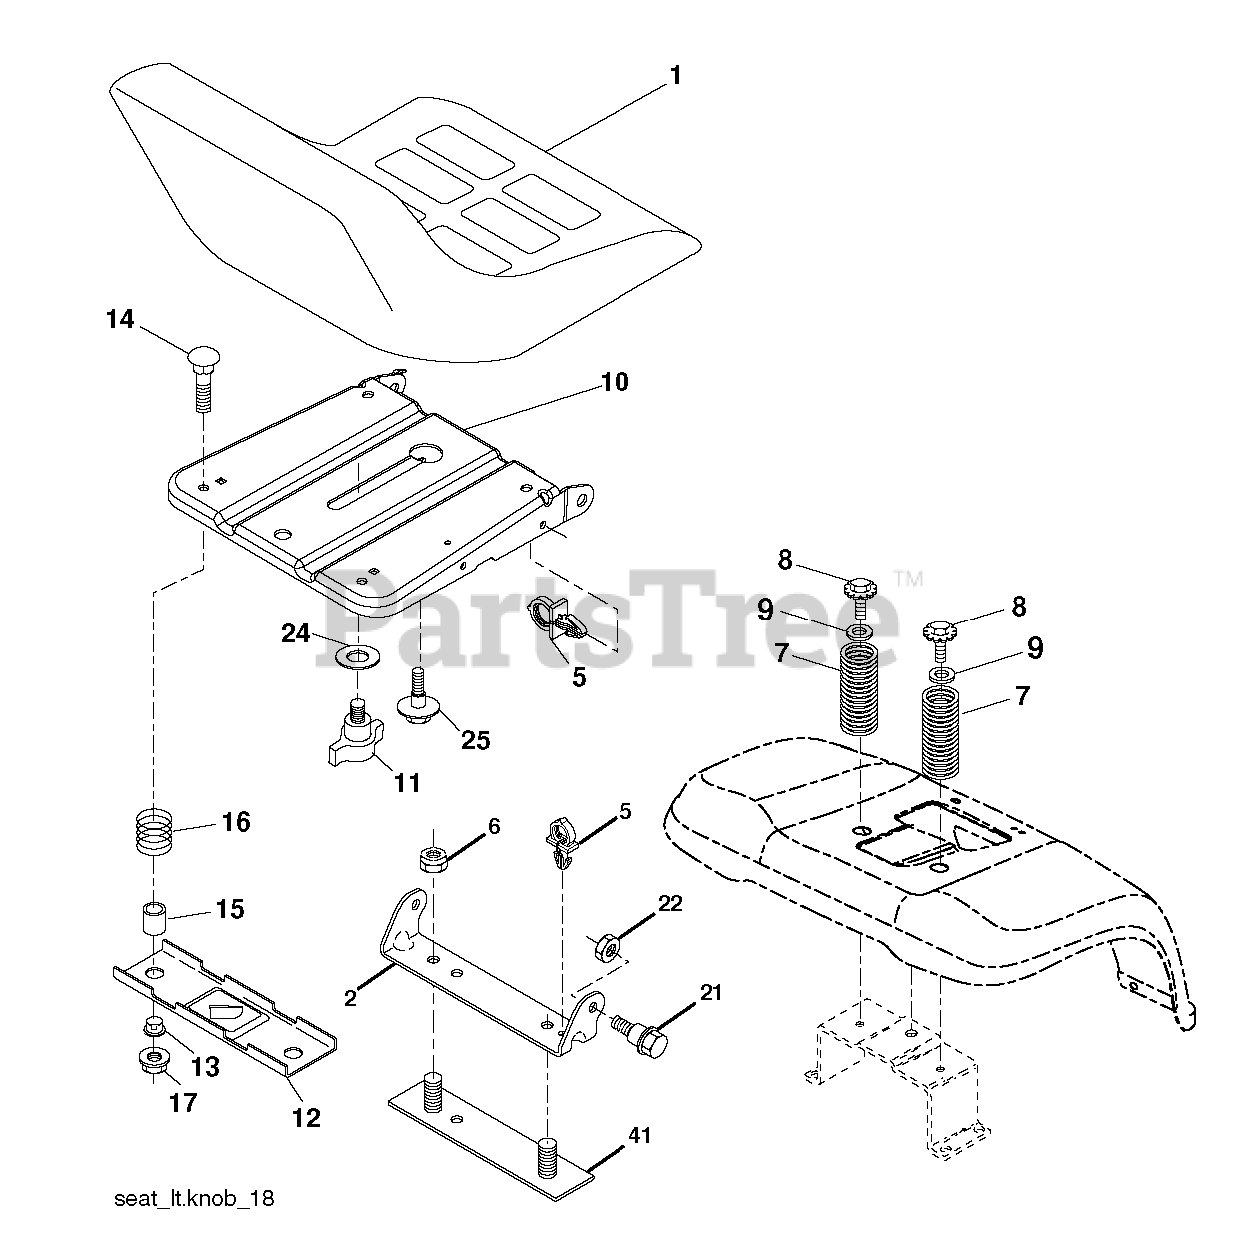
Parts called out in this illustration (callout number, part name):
1	RP SEAT
2	SEAT PIVOT BRKT
6	NUT
7	SPRING COMPRESSION
8	SCREW 3/8-16X1
9	WASHER
10	PAN.ASM.SEAT.1SLOT
11	KNOB.SEAT.ADJ.WINGNUT
12	BRKT.MNTNG.SWITCH.SEAT.BLACK
14	BOLT.ROUND.HEAD.SQUARE.NECK
15	SPACER SPLIT 28X.96
17	NUT T
21	BOLT.SHOULDER.5/16-18
22	NUT.71038.31-18.HEX.NYLOCK
25	BOLT,SHOULD
41	STRAP
